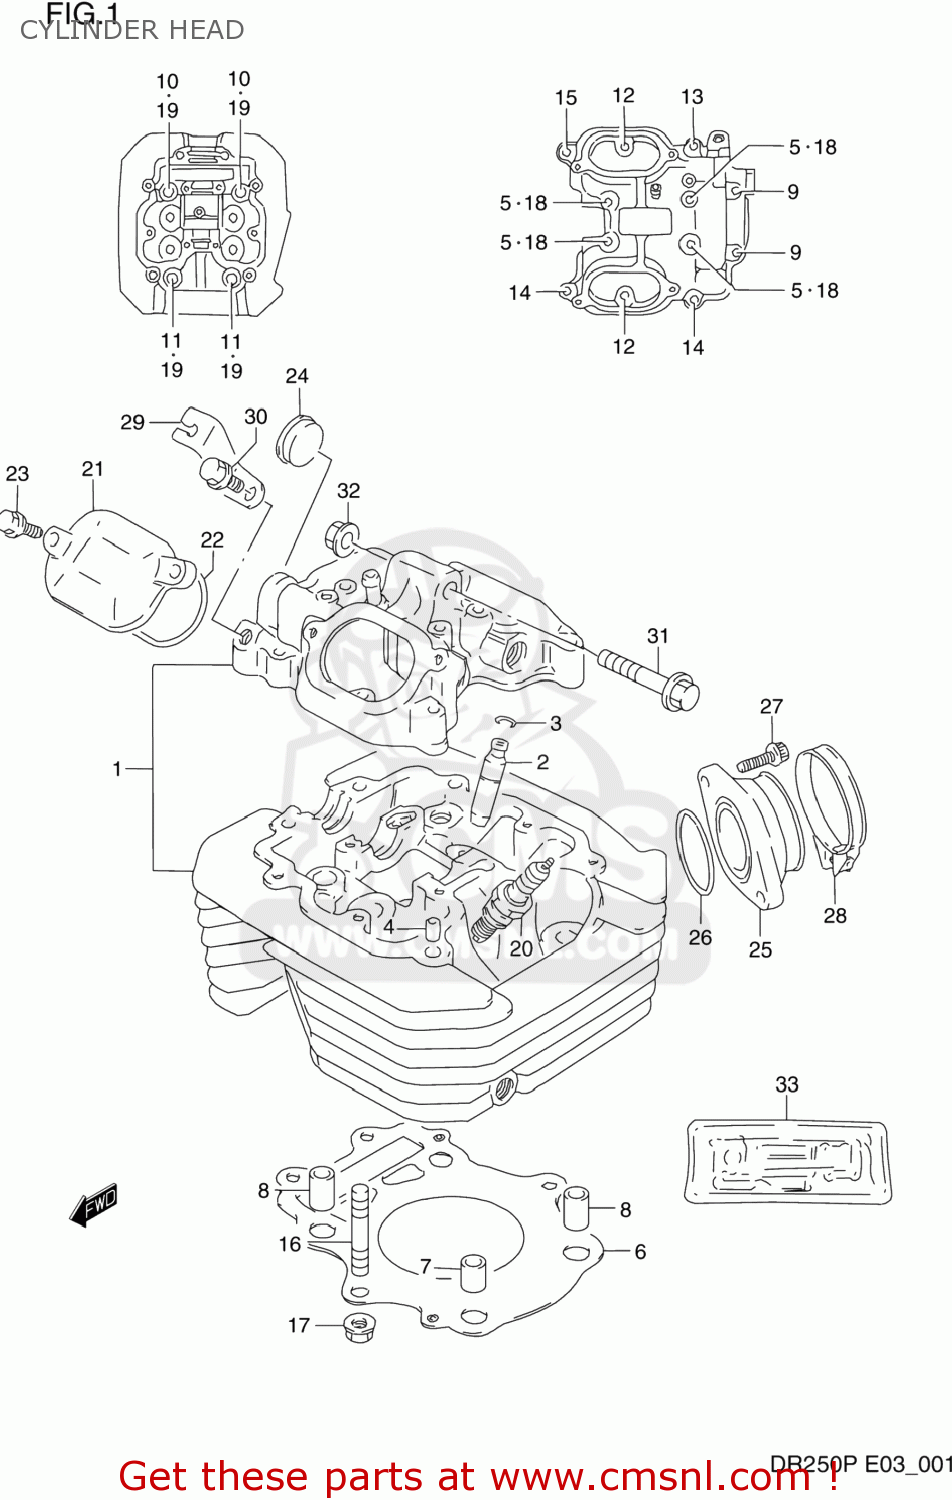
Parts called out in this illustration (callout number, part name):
1	HEAD ASSEMBLY,CYLINDER
2	GUIDE,VALVE
3	RING,SNAP
4	PIN(6.2X8X11)
5	BOLT(6X55)
6	GASKET,CYLINDER HEAD (NAS)
7	PIN
8	PIN(10.4X13X22)
9	BOLT(6X115)
10	BOLT(10X180)
11	BOLT(10X155)
12	BOLT 6X25
13	BOLT
14	BOLT(6X35)
15	BOLT(6X39)
16	BOLT,STUD
17	NUT
18	GASKET(5.8X13X1.2) (NAS)
19	WASHER (10.5X22X2.3)
20	PLUG,SPARK(DPR9EA-9)
21	CAP,INSPECTION
22	GASKET (NAS)
23	BOLT 6X20
24	PLUG,OD:30
25	PIPE,INTAKE
26	O RING(D:2.4,ID:39.7)
27	PLUG ,6X20
28	CLAMP
29	LEVER,DECOMP SHAFT RH
30	BOLT, LOWER
31	BOLT(8X65)
32	NUT
33	GASKET (NAS)
